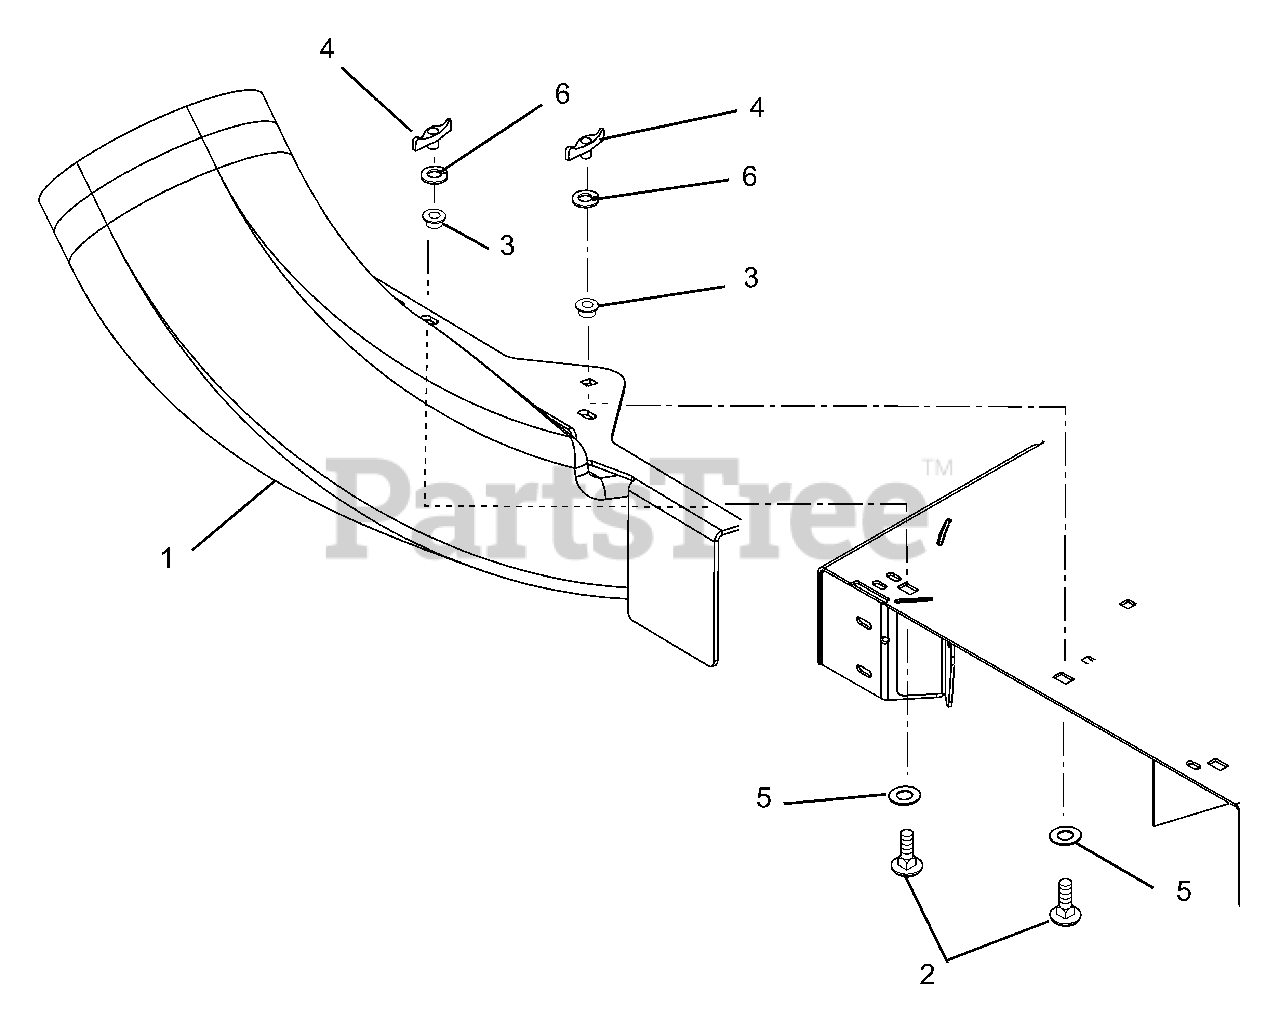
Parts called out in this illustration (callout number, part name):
1	ASSY, BAGGER BOOT
2	@BLT-RDHDSHSQNK.38-16X1.0 G5YZ
3	RETAINER, .38 PUSH-ON
4	NUT-WING .38-16
5	WSHR-FL-STL .52X.827X.062 YWZC
6	WSHR-LK .375X.115 HVY YWZC
